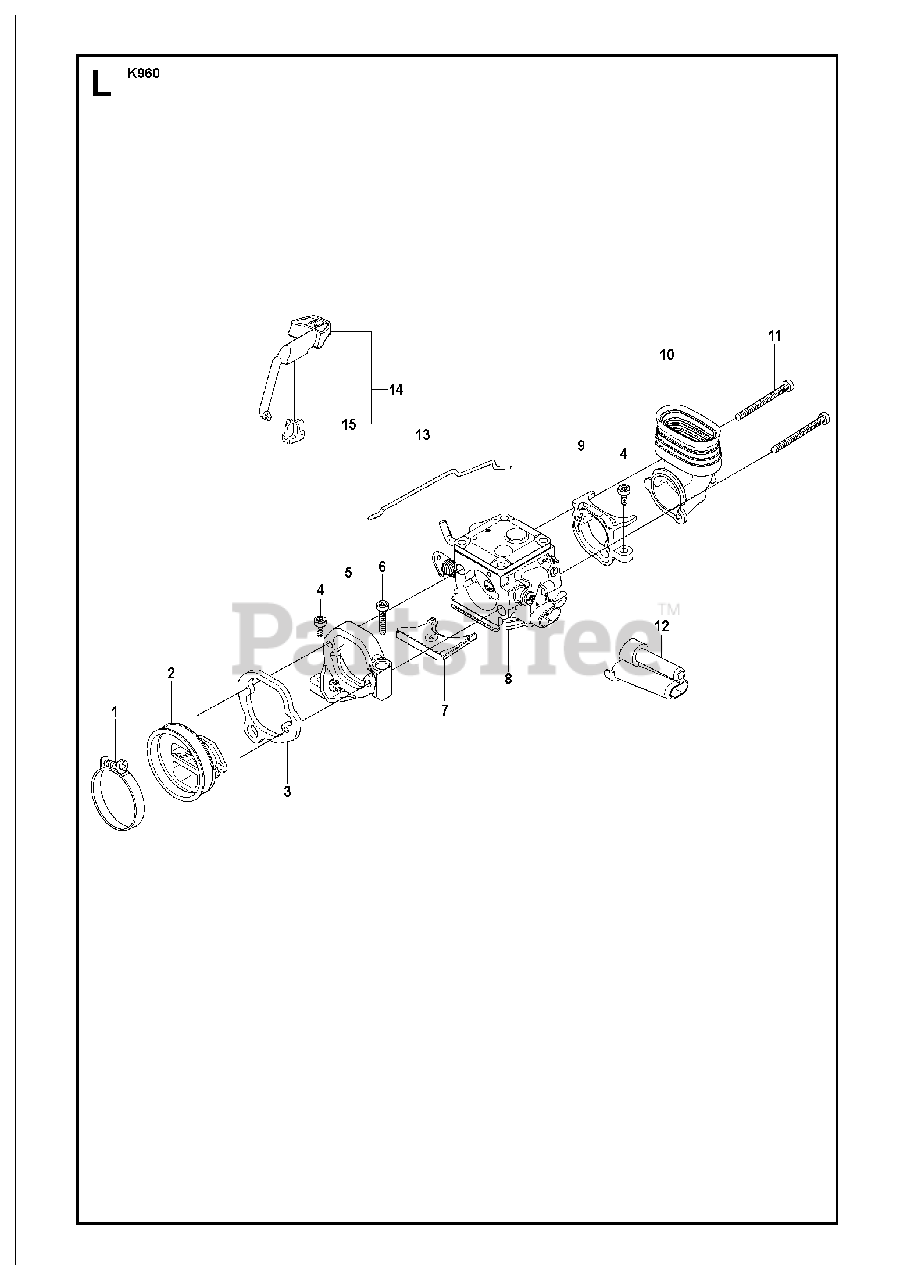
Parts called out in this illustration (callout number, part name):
1	HOSE CLAMP
4	SCREW ITXSCM
6	SCREW ITXSCM
8	CARBURETTORWalbro RWJ-2
11	SCREW ITXSCM
12	CHISEL GUIDE
13	THROTTLE ROD
14	CHOKEIncl. 15
15	WEAR PROTECTION
